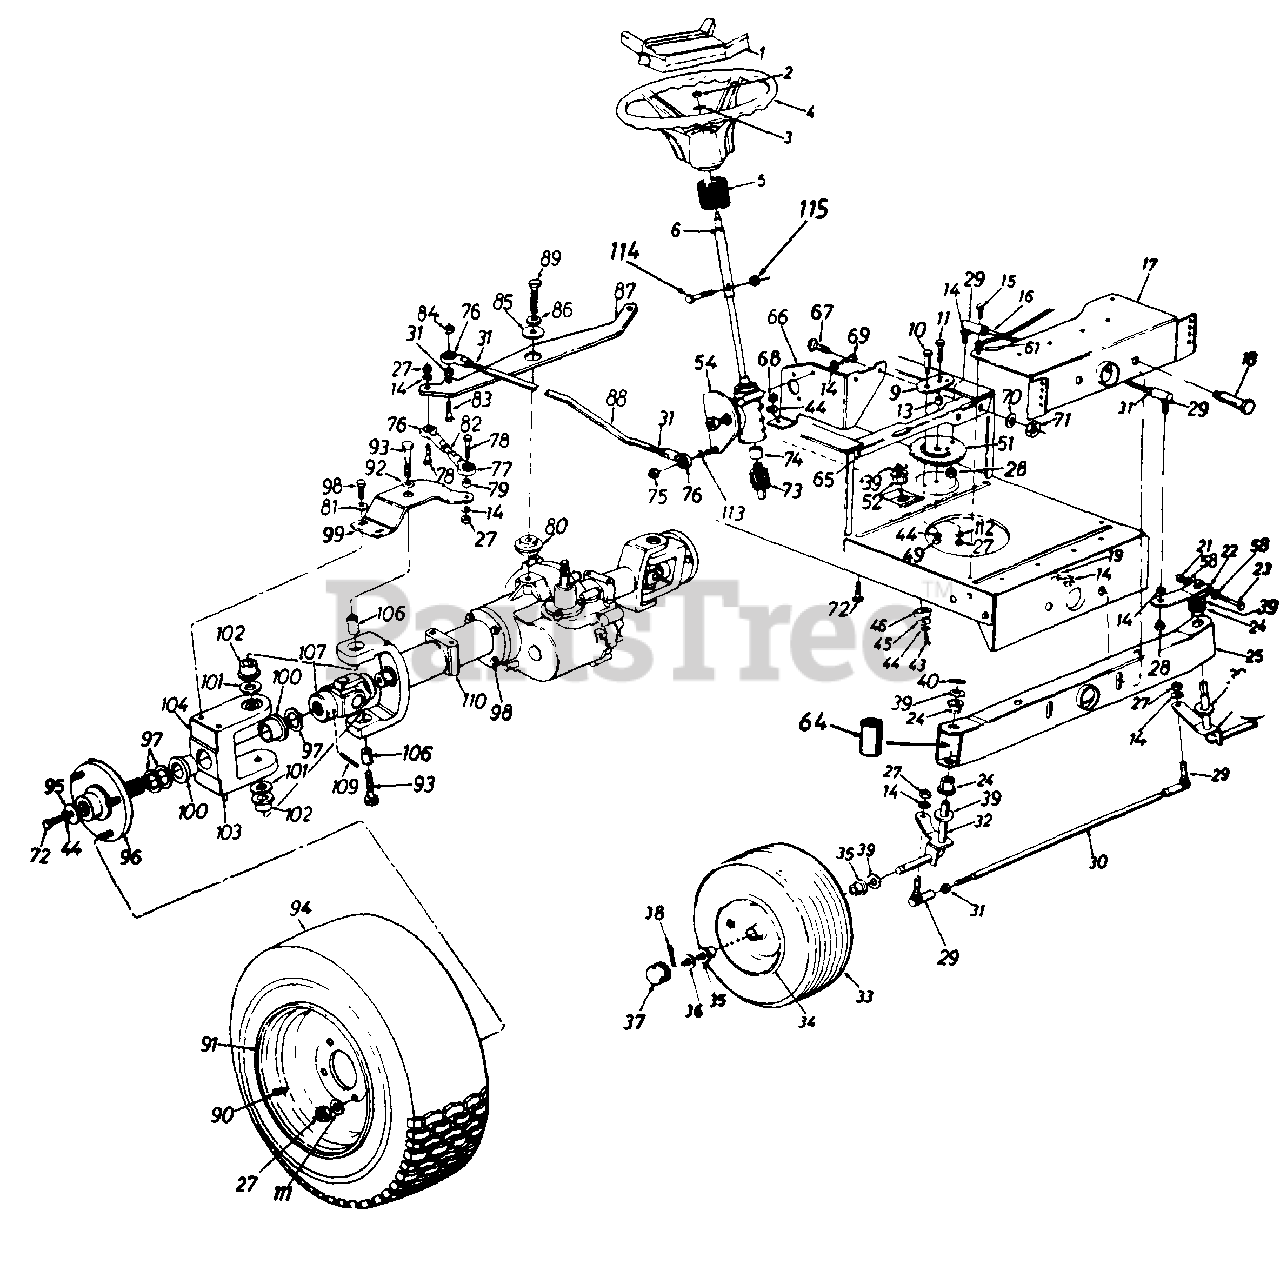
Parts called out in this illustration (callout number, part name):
1	Steering Wheel Insert
2	Hex L-Nut 5/16-24 Thd.
3	Belleville Wash. .345" I.D.
4	Steering Wheel (4 Spoke)
5	Steering Bellow
6	Upper Steering Shaft Ass'y.
9	Retainer Plate
10	Shoulder Bolt .437" Dia. x .35" Lg. 5/16-18 Thd.
11	Hex Bolt 3/8-24 x 1.0" Lg. (Grade 5)
13	Spacer.380" I.D. x .625" O.D. x .227"
14	L-Wash. 3/8" I.D.
15	Hex Wash. Hd. Self-Tap Scr.
16	Steering Drag Link
18	Shoulder Bolt .498" Dia. x 2.04" Lg. 3/8-16 Thd.
19	Hex Nut 3/8-16 Thd.
21	Hex Cent. L-Nut 5/16-24 Thd.
22	Steering Arm Front Axle
23	Hex Bolt 5/16-24 x 2.00" Lg. (Grade 5)
24	Hex Flg. Brg..634" I.D.
27	Hex Nut 3/8-24 Thd.
28	Hex Jam Nut 3/8-24 Thd.
29	Ball Joint 3/8-24 Thd.
30	Tie Rod
31	Hex Jam Nut 3/8-24 Thd.
32	Front Axle Ass'y.- R.H.
33	Wheel Ass'y. Comp.
34	Front Wheel Rim Only
35	Bearing
36	Fl-Wash. .635" I.D. x 1.59" O.D.
37	Front Hub Cap
38	Cotter Pin 1/8" Dia. x 1.25" Lg.
39	Fl-Wash. .640" I.D. x .24" O.D.
40	Push Cap
43	Hex L-Bolt 5/16-18 x .62"
44	L-Wash. 5/16" I.D.
45	Fl-Wash. .33" I.D. x 1.25" O.D.
46	Spacer (Plastic)
49	Hex Nut 5/16-18 Thd.
51	Steering Gear Segment
52	Hex Flg. Brg. .634 I.D.
54	Steering Box Ass'y. Comp.
58	Wave Wash..32" I.D. x .62"
61	Ext. L-Wash. 5/16" I.D.
64	Spacer
65	Horizontal Cross Bracket
66	Vertical Mounting Bracket
67	Hex Bolt 1/4-28 x .75" Lg.
68	Hex Nut 5/16-24 Thd.
69	Hex Bolt 3/8-16 x 1.0" Lg.
70	Bell-Wash. .265" I.D. x .75"
71	Hex Nut 1/4-28 Thd.
72	Hex Bolt 5/16-24 x .75" Lg.
73	Pinion Shaft
74	Steering Shaft Splined Coupler
75	Hex L-Nut 3/8-24 Thd.
76	Rod End 3/8-24 Thd. - R.H.
77	Rod End 3/8-24 Thd. - L.H.
78	Hex Bolt 3/8-24 x 1.5" Lg. (Gr. 5)
79	Spacer .38" I.D. x 625"
80	Shld. Spacer .51" I.D.
81	Bell-Wash. 38" I.D. x .88"
82	Tie Rod
83	Hex Bolt 3/8-24 x 1.25" Lg.
84	Hex Patch L-Nut 3/8-24 Thd.
85	Fl-Wash. .531" I.D. x 1.75"
86	Bell-Wash. .505" I.D. x 1.0"
89	Hex Bolt 1/2-13 x 1.5" Lg. (Gr 5)
90	Air Valve
93	Hex Bolt 1/2-20 x 1.75" Lg. (Gr. 5)
95	Fl-Wash. .33" I.D. x 1.25"
96	Wheel Flange Ass'y.
97	Fl-Wash. 1.0" x 1.56"
98	Hex Bolt 3/8-24 x 1.25" Lg.
101	Fl-Wash. .76" 1.O. x 1.5"
102	Flange Brg. 3/4" I.D.
103	Grease Fltting
104	Wheel Brg. Housing
106	Pivot Sleeve
107	U-Joint
109	Grooved Roll Pin 1.0" Lg.
110	Axle Horn Ass'y.
111	Bell-Wash. .38" I.D. x .88"
112	Bell-Wash. .39" I.D. x 1.38"
113	Fl-Wash. .385" I.D. x .62"
114	Hex Bolt 1/4-20 x 1.31" Lg.
115	Hex Ins. L-Nut 1/4-20 Thd.
